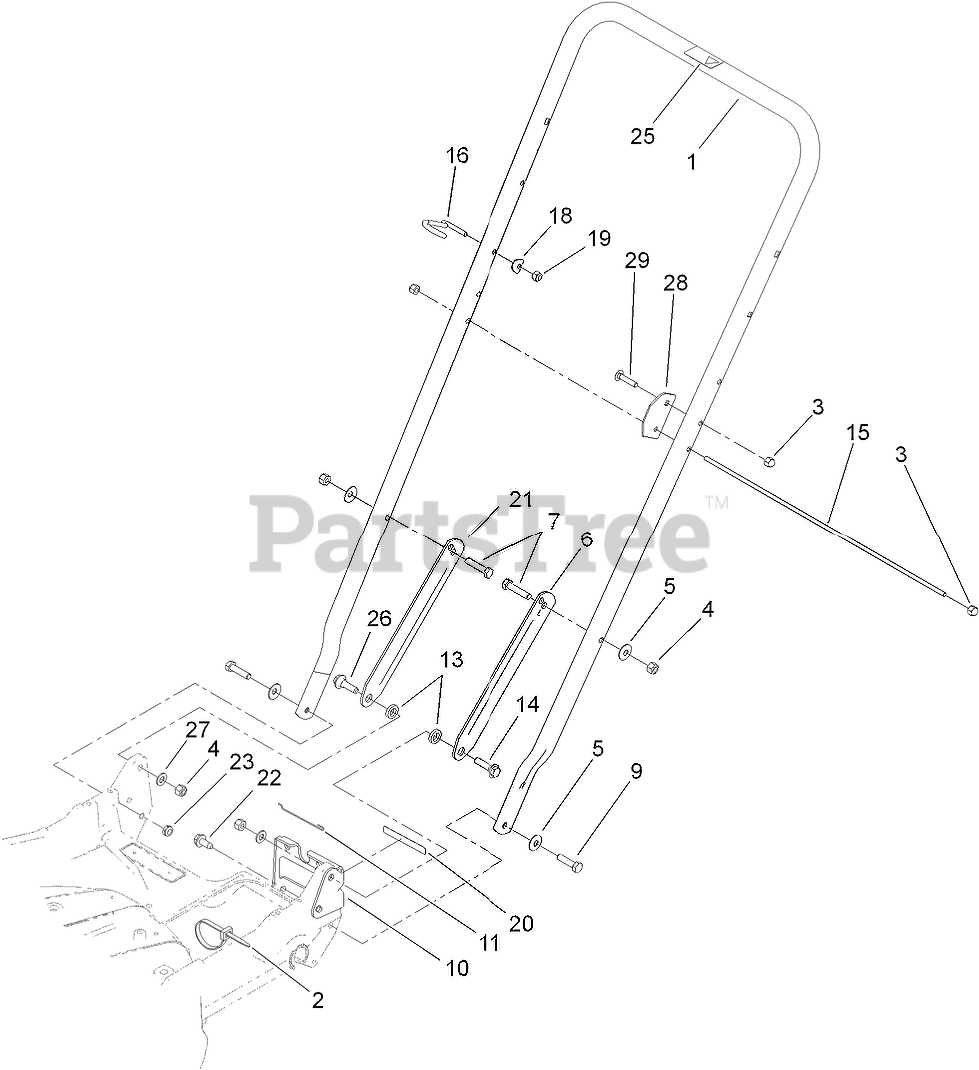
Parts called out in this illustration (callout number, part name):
2	TIE-CABLE
3	NUT-CAP
4	NUT-LOCK, NI
5	WASHER-BELLEVILLE
6	LATCH-HANDLE, LH
7	SCREW-HH
9	SCREW-HH
10	BRACKET-ADJUSTMENT, TRACTION
11	RETAINER-CABLE
13	SPACER
14	SCREW-SHOULDER
15	ROD-SUPPORT, BAG
16	GUIDE-ROPE
18	WASHER
19	NUT-LOCK, NI
20	DECAL-POSITION, GEAR
21	LATCH-HANDLE, RH
22	SCREW-HWHTF
23	NUT-LOCK, NI
25	DECAL-PROTECTION, EAR
26	SCREW-SHOULDER
27	WASHER-PLAIN
28	PLATE-ALIGNING, BAG
29	SCREW-CARR
